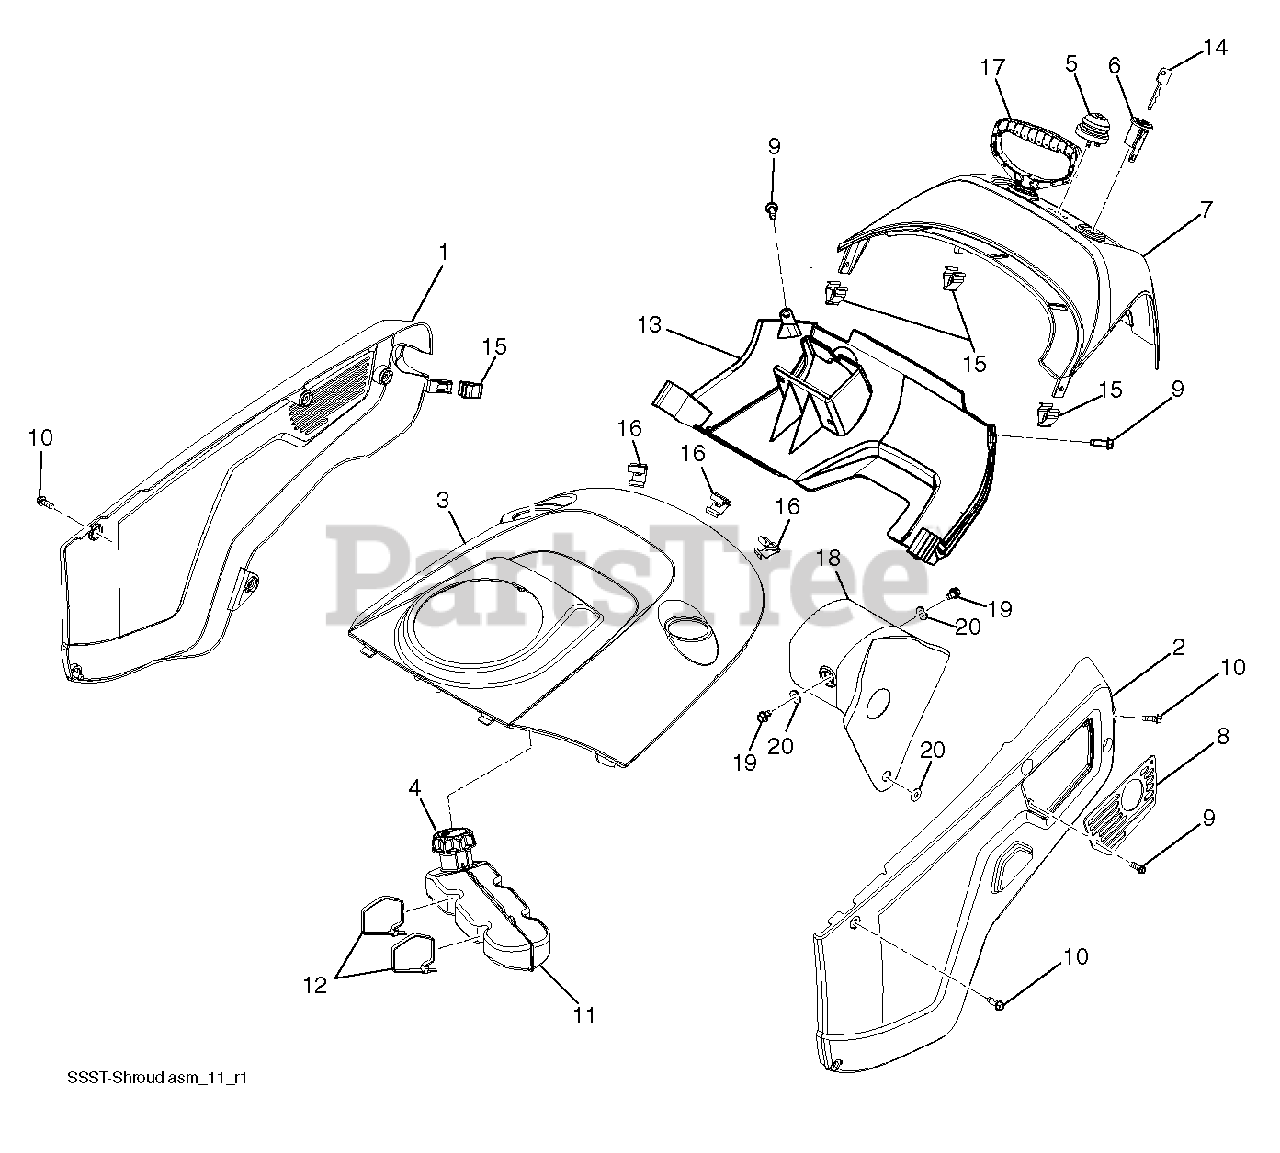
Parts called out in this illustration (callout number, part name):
4	CAP ASM.FUEL.2.25"FR.
5	RP BULB.PRIMER
6	KEY HOUSING
7	TOP.REAR.COVER
8	PLATE.EXHAUST.PNT.
9	SCREW.HX.13X.750
10	SCREW.PAN.HD.TORX.1/4-20X.750
11	TANK.FUEL.ASM
12	TIE.CABLE.24.5X.29.NYLON.WHITE
13	COVER REAR.LOWER.SSST.BLACK
14	KEY
17	RP HANDLE.STARTER
18	COVER.MUFFLER.136CC/208CC.LCT
19	BOLT.M6-1.0X16MM
20	WASHER
